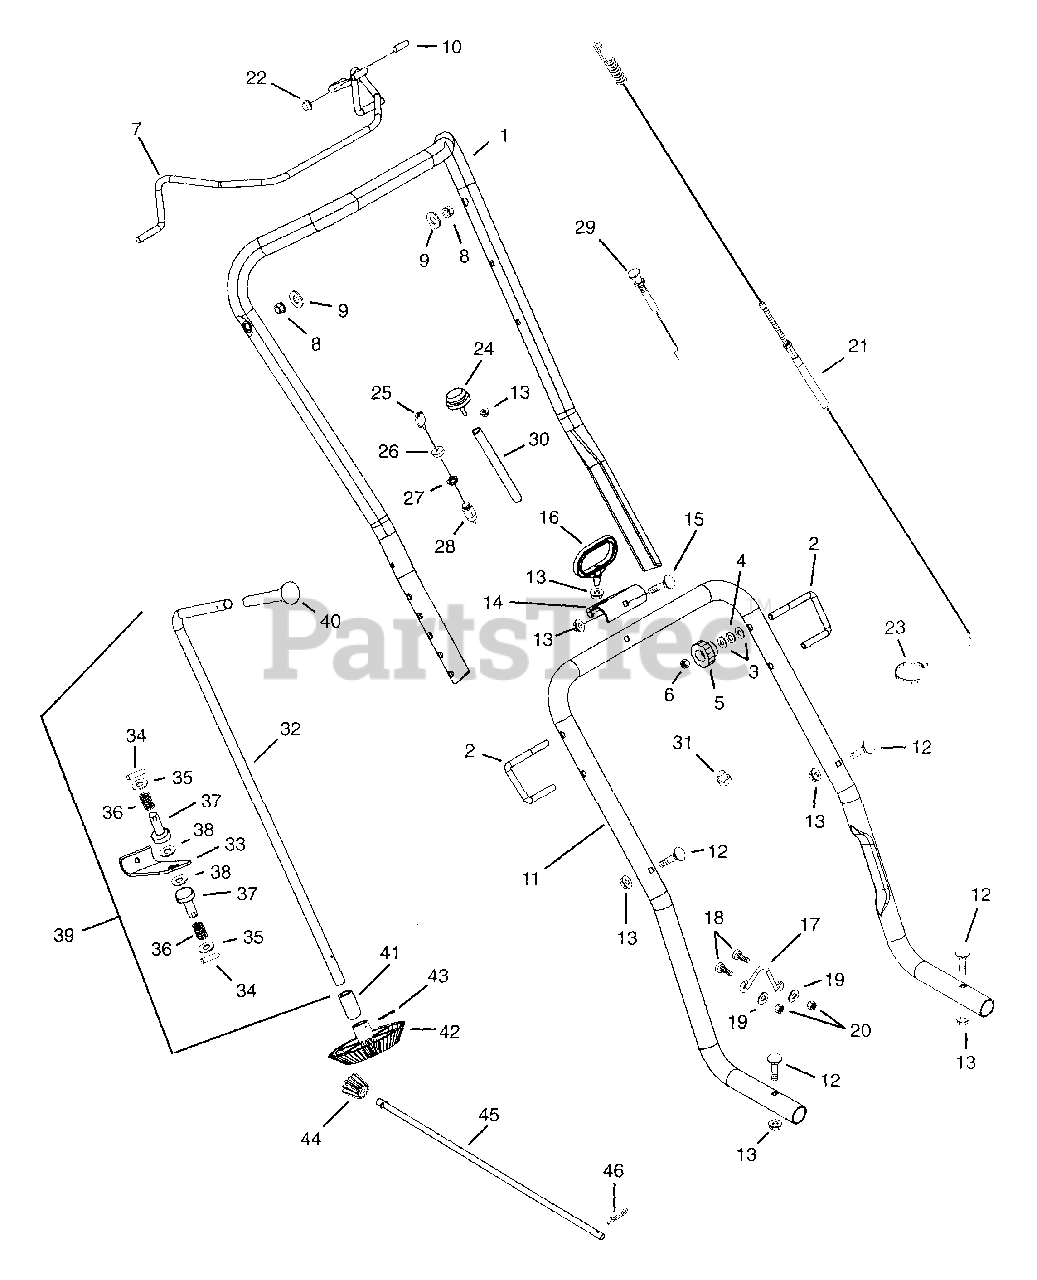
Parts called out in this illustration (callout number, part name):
1	HANDLE BAR-UPPER
2	J BOLT .31-18
3	@WSHR-FL-STL.38X.875X.083 YWZC
4	@WSHR-LK .31X.078 REG YWZC
5	KNOB
6	@NUT-LK-CTR .31-18 YWZC
7	BAIL SS LF
8	BSHG-FLG .325X.444X.440X.560
9	@WSHR-FL-STL.344X.688X.065YWZC
10	CAP, VINYL, .25 ID
11	HANDLE BAR-LOWER
12	BLT-RDHDSQNK .25-20X1.75 G5YZ
13	NUT-LK-FLG .250-20 PL BLK
14	BRKT-STARTER HANDLE
15	BLT-RDHDSQNK .25-20X1.50 PL BL
16	HANDLE, RECOIL START
17	GUIDE-ROPE
18	@SCR-MCH 10-24X.75 HWH YWZC
19	@WSHR-FL-STL.219X.50X.049 YWZC
20	@NUT-LK-NYL 10-24 W/INSRT YWZC
21	CABLE ASS,Y SS LITE
22	NUT, PUSH .25 DIA.
23	CABLE TIE LG 5-1/2
24	PRIMER ASSY
25	KEY -W/CAP
26	CAP - IGNITION SWITCH
27	NUT-PANEL .625-32 GRECO
28	KEY SWITCH ASSEMBLY
29	CONTROL-CHOKE 3 HP
30	LINE-PRIMER
31	PLUG-HOLE .50 DIA
32	CRANK-CHUTE
33	SUPPORT-CHUTE CRANK
34	PIN-ROLL .125X1.38
35	WSHR-FL-STL.754X1.125X.062YWZC
36	SG-COMP .105X.970X2.75 WLD55.5
37	SLEEVE-SPRING THRUST
38	WSHR-FRICTION .53X1.00X.094
39	CRANK-CHUTE ASSY
40	KNOB
41	BSHG-SLV .510X.753X2.00
42	GEAR-CRANK TRANSFER 48T
43	@PIN-CTR .16X1.25 EXTPRSQCT YZ
44	PINION-CRANK TRANSFER 12T
45	SHAFT CHUTE CRANK TRANSFER
46	PIN-HAIR INT .08X.38X1.42 YWZC
